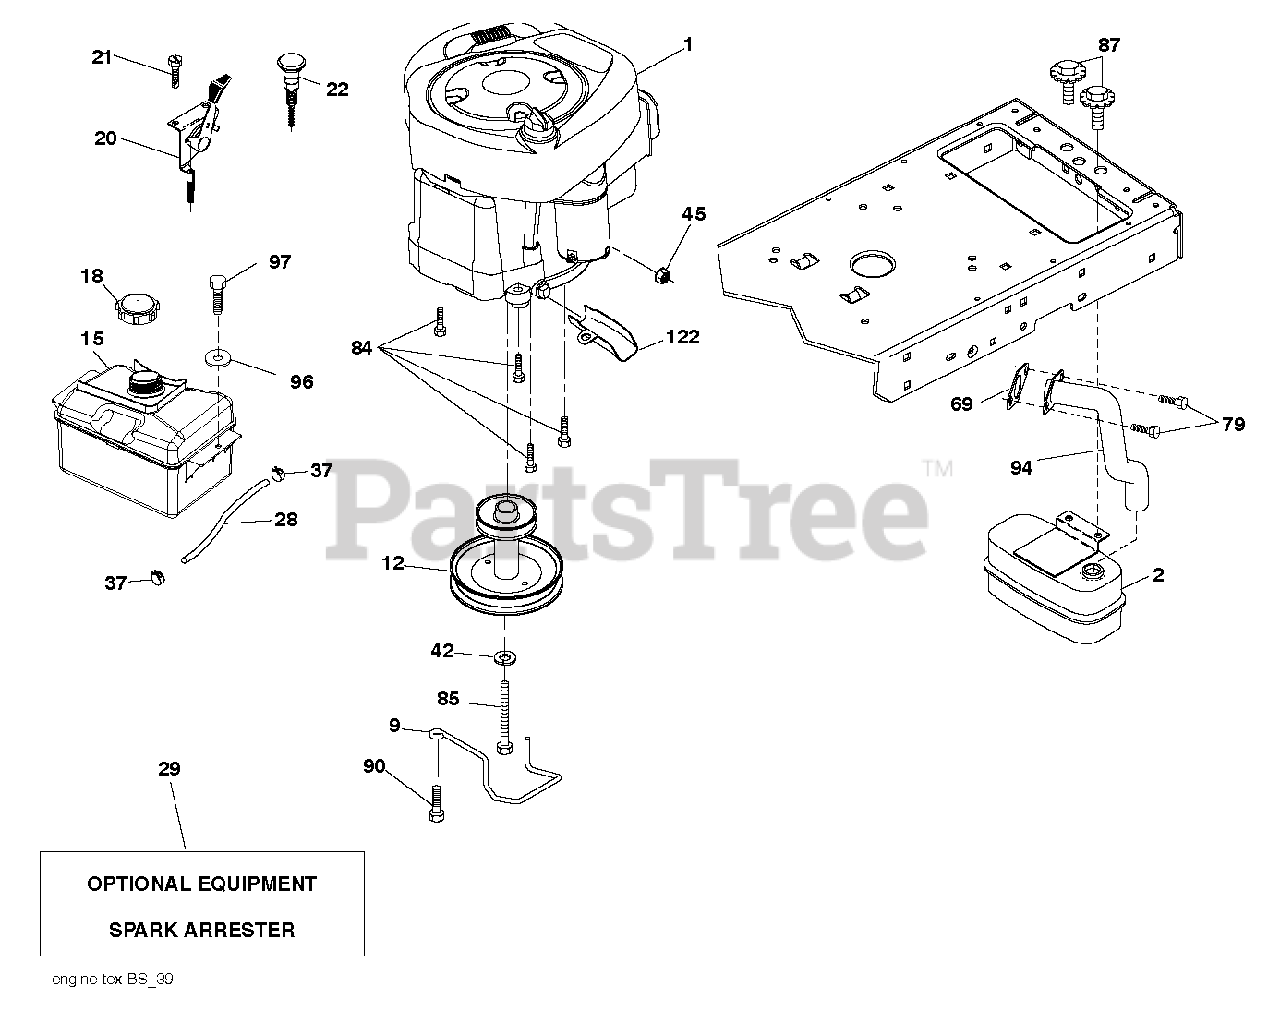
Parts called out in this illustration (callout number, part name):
2	MUFFLER.SINGLE.CYL.KOHL/B&S
9	KEEPER.BELT.ENGINE.4.2
12	PULLY ENGINE
15	TANK FUEL FRT 1.5 GAL
18	CAP ASM.FUEL.2.25"FR.
20	CONTROL.TH/CK.C.
21	SCREW.#10 X 0.750.BOS THREAD
28	LINE.FUEL.20
29	ARRESTER SPARK (OPTIONAL)
37	HOSE CLAMP
42	LOCKWASHER
45	NUT
69	REPL BY 532 27 22-93
79	SCREW.SOCKET HD.5/16-1
84	SCREW
85	BOLT HEX 7/16-20X4-1/4"
87	BOLT, 5/16-18 X 1 3/4
90	SCREW 3/8-16X1
94	EXHAUST.TUBE.B&S.
97	SCREW HEXWSHR 1/4-20X3/4
122	EXTENSION DRAIN OIL
